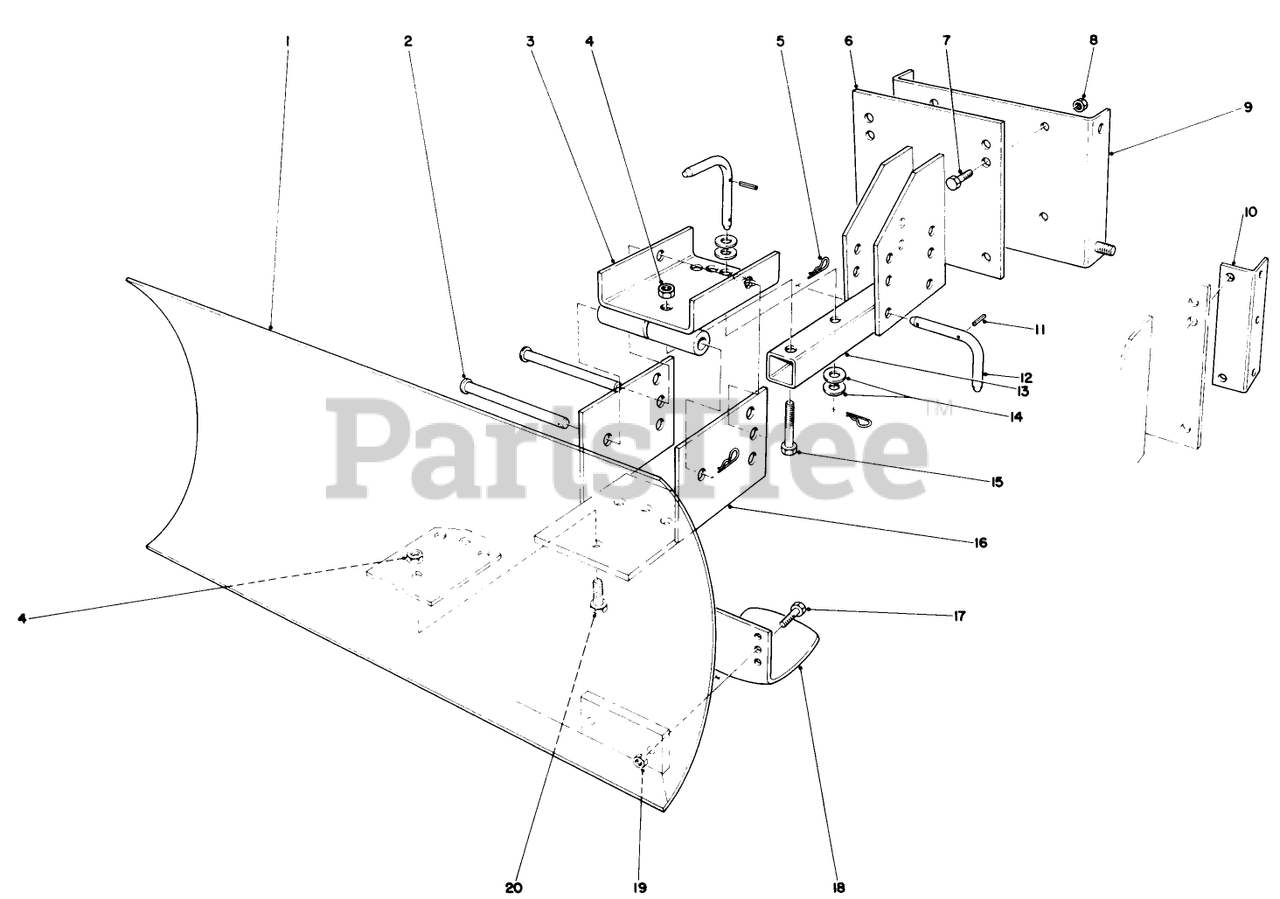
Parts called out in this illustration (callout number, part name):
1	Blade
2	PIN-CLEVIS
3	Swivel Bracket
4	1/2-13 CONELOCK NUT
5	PIN-HAIR
6	Mounting Plate
7	SCREW-HH
8	NUT-LOCK, CONE
9	Mounting Plate (Used with 826 & 1132 Units only)
10	Mounting Rail (used with 421 units only)
11	PIN-SPRING
12	Pivot Pin (Incl. Ref. #11)
13	Blade Tongue
14	WASHER-FLAT
15	SCREW-HH
16	Blade Adjustment
17	SCREW-HH
19	NUT-LOCK, CONE
20	SCREW-HH
